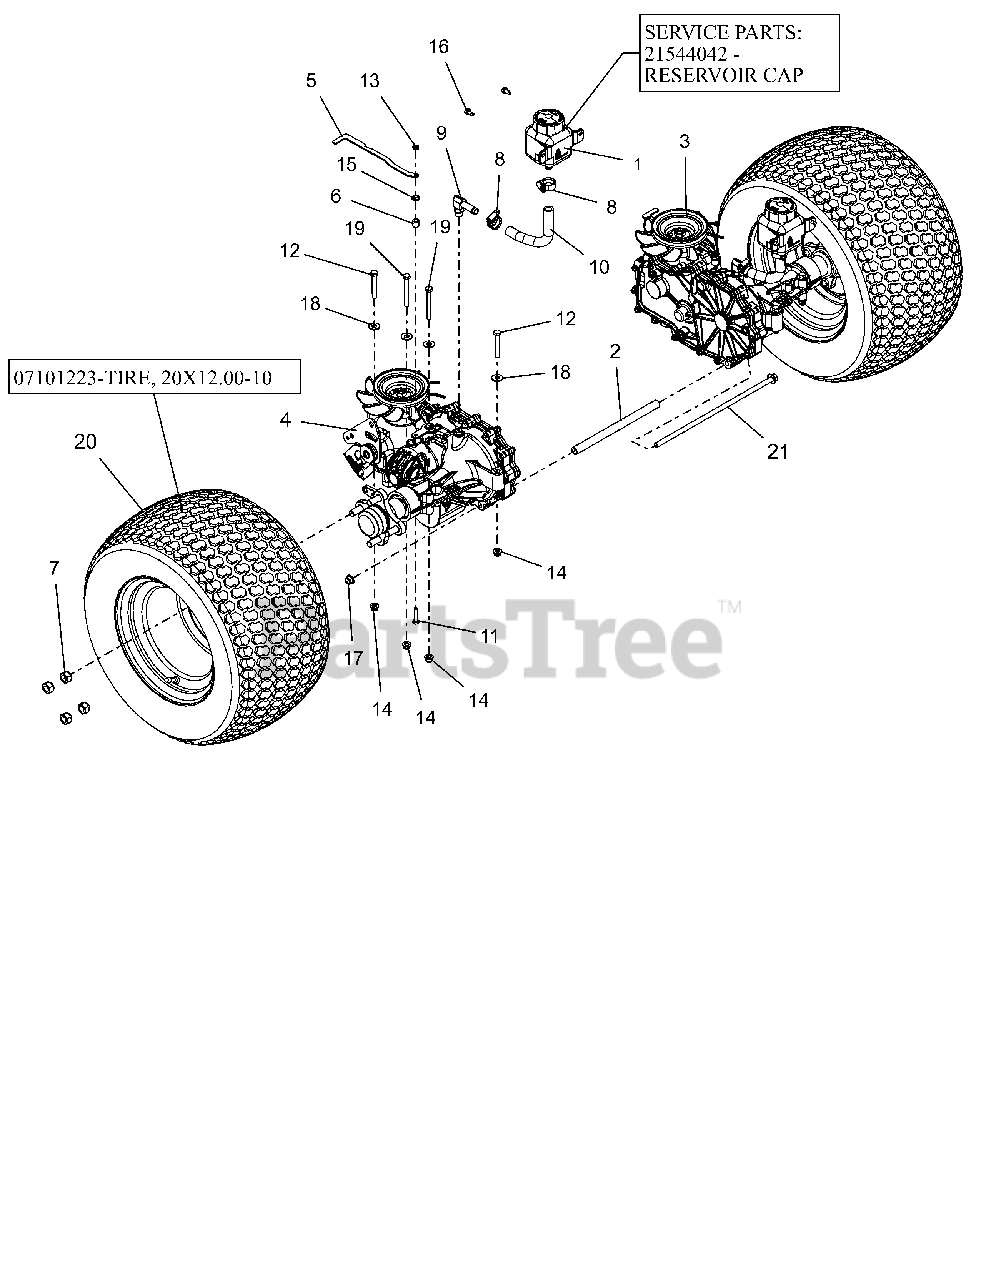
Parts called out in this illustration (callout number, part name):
1	TANK, EXPANSION
1	CAP, HYDRO RESERVOIR REPLAC.
2	SPCR, TRANSAXLE .406 ID X .630 OD X 9.27 (BLACK)
3	TRANSAXLE,ZT2800 LH
4	TRANSAXLE,ZT2800 RH
5	BRKT, DUMP VALVE
6	BSHG-SLV .265X.500X.500
7	WHEEL NUT .500-20 YZ
8	CLAMP,.88 DIA. HOSE
9	FITTING, HYD (90 DEG)
10	HOSE, FORMED LH XL
11	@BLT-HEX .25-20X1.25 GR5 YWZC
12	@BLT-HEX .31-18X2.25 GR5 YWZC
13	NUT-LK-CTR JAM .25-20 YWZC
14	@NUT-LK-NYL-FLG .31-18 YWZC
15	@NUT-SPNLK-FLG .25-20 YWZC
16	SCR-TAP .25-20X.50 HWH TR YWZ
17	NUT-LK-CTR-FLG .375-16 GF ZCC
18	@WSHR-FL-STL.38X.875X.083 YWZC
19	@BLT-HEX .31-18X2.75 GR5 YWZC
20	ASM, WHL/TIRE 20X12.00-10
20	TIRE, 20X12.00-10 (OTR)
21	BLT, HEX-FLG 0.375-16X13 GR5 ZC120
